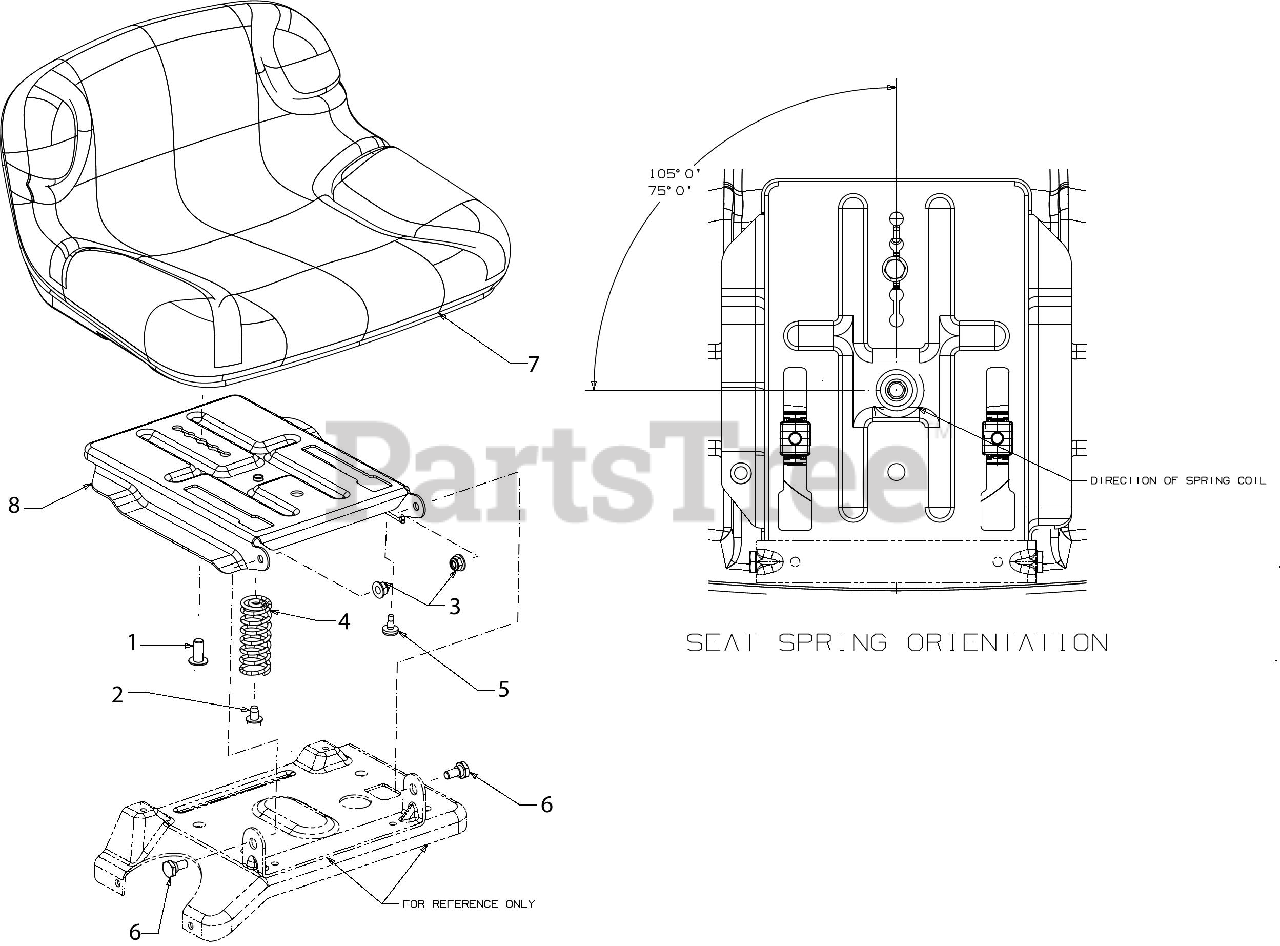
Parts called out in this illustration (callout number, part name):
1	SCREW 3/8-16 x .875 GR5
2	SCREW 5/16-18 x .500
3	FLANGE LOCK NUT 5/16-18
4	SEAT SPRING
5	RUBBER BUMPER
6	SHOULDER SCREW .437
7	LOW BACK SEAT (BLACK NO OPS)
8	MANUAL SEAT ADJUSTMENT BRACKET
